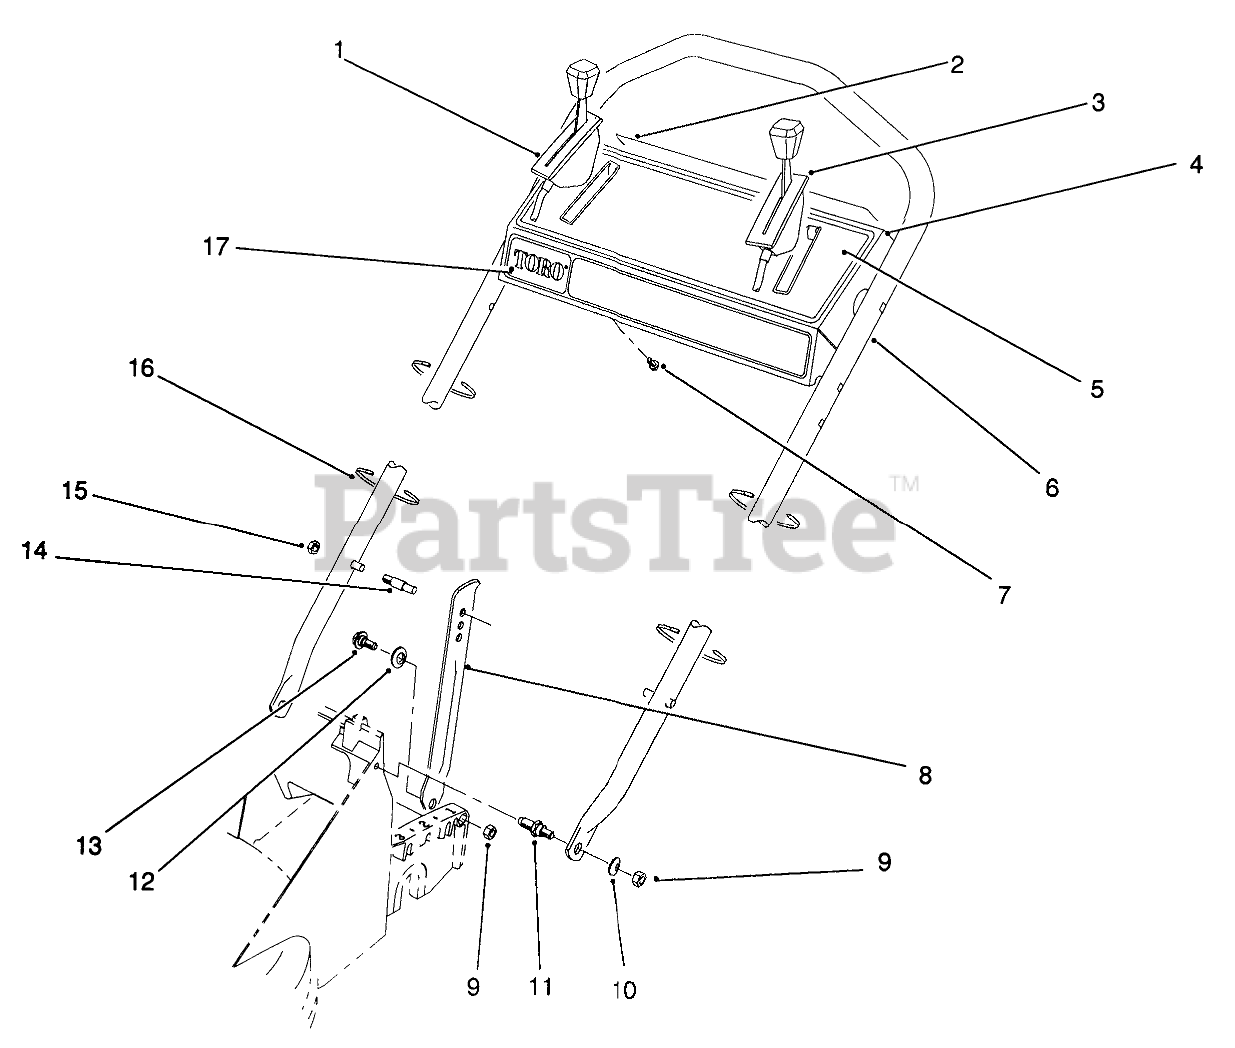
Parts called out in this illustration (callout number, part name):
1	Control-Ground Speed
2	DECAL - PANEL, REAR
3	ControI-Throttle Bend Type #2 Sheath Lg. 44-3/4" Wire Lg. 2-1/2"
4	Control Panel Assembly (Incl. Ref. #2 & 5)
5	DECAL - INSTRUCTION
6	HANDLE
7	SCREW-HWHTF
8	HANDLE LATCH
9	NUT-LOCK, NI
10	WASHER-PLAIN
11	SCREW - SHOULDER STUD
12	NYLON WASHER
13	SCREW-SHOULDER
14	HANDLE PIN
15	NUT-LOCK, NI
16	TIE-CABLE
17	DECAL - TORO PANEL
